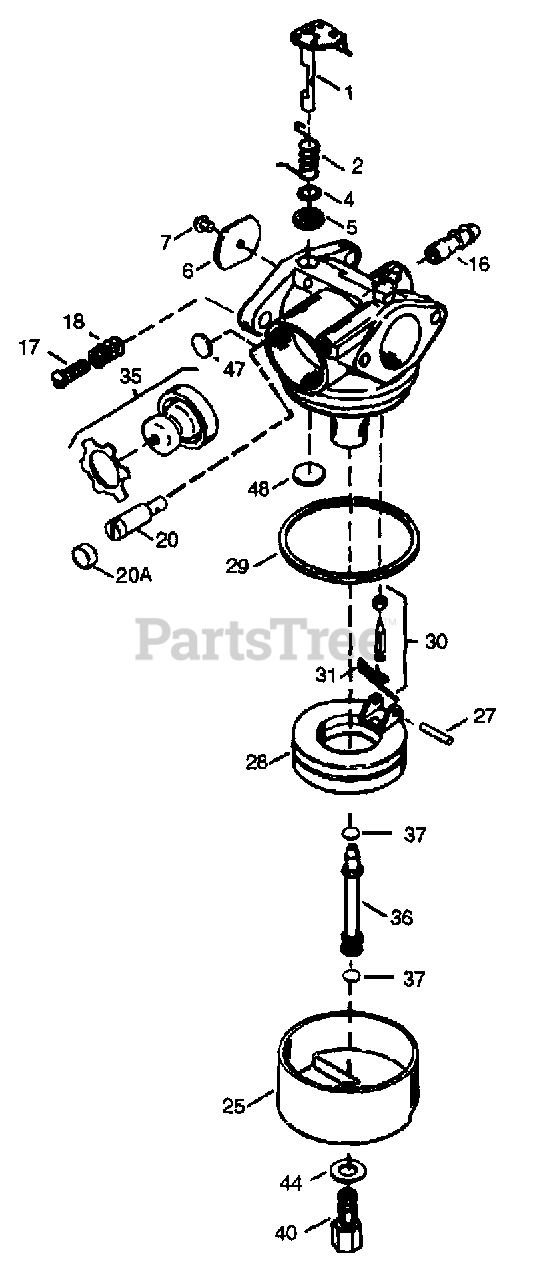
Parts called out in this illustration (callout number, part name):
1	Throttle Shaft & Lever Assy
2	Throttle Return Spring
4	Dust Seal Washer
5	Dust Seal
6	Throttle Shutter
7	Shutter Screw
16	Fuel Fitting
17	Throttle Crack Screw/Idle Speed Screw
18	Tension Spring
20	Idle Restrictor Screw
20A	Idle Restrictor Screw Cap
25	Float Bowl
27	Float Shaft
28	Float
29	Float Bowl "O" Ring
30	Inlet Needle, Seat & Clip
31	Spring Clip
35	Primer Bulb/Retainer Ring
36	Main Nozzle Tube
37	"O" Ring, Main Nozzle Tube
40	High Speed Bowl Nut
44	Bowl Nut Washer
47	Welch Plug, Idle Mixture Well
48	Welch Plug, Atmospheric Vent
